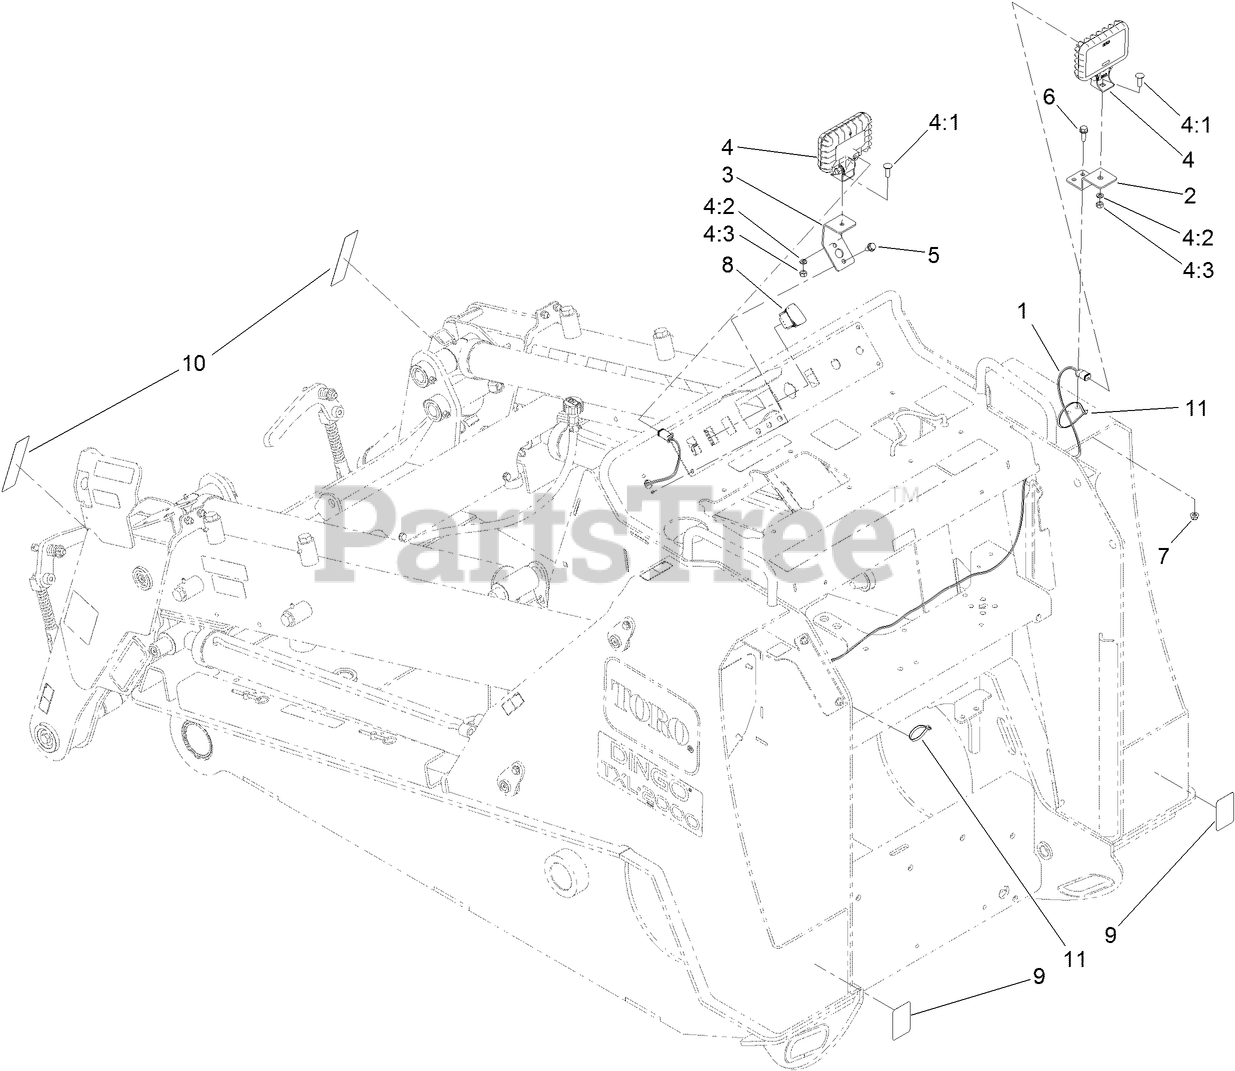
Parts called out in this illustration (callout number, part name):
1	HARNESS-WIRE, LIGHT KIT
2	BRACKET-LIGHT, RH
3	BRACKET-LIGHT, LH
4	LIGHT-WORK, LED
4:1	SCREW-CARR
4:2	WASHER-LOCK
4:3	NUT-HEX
5	SCREW-HWH
6	SCREW-HHF
7	NUT-HF, NI
8	SWITCH
9	REFLECTOR
10	TAPE-REFLECTIVE
11	TIE-CABLE
